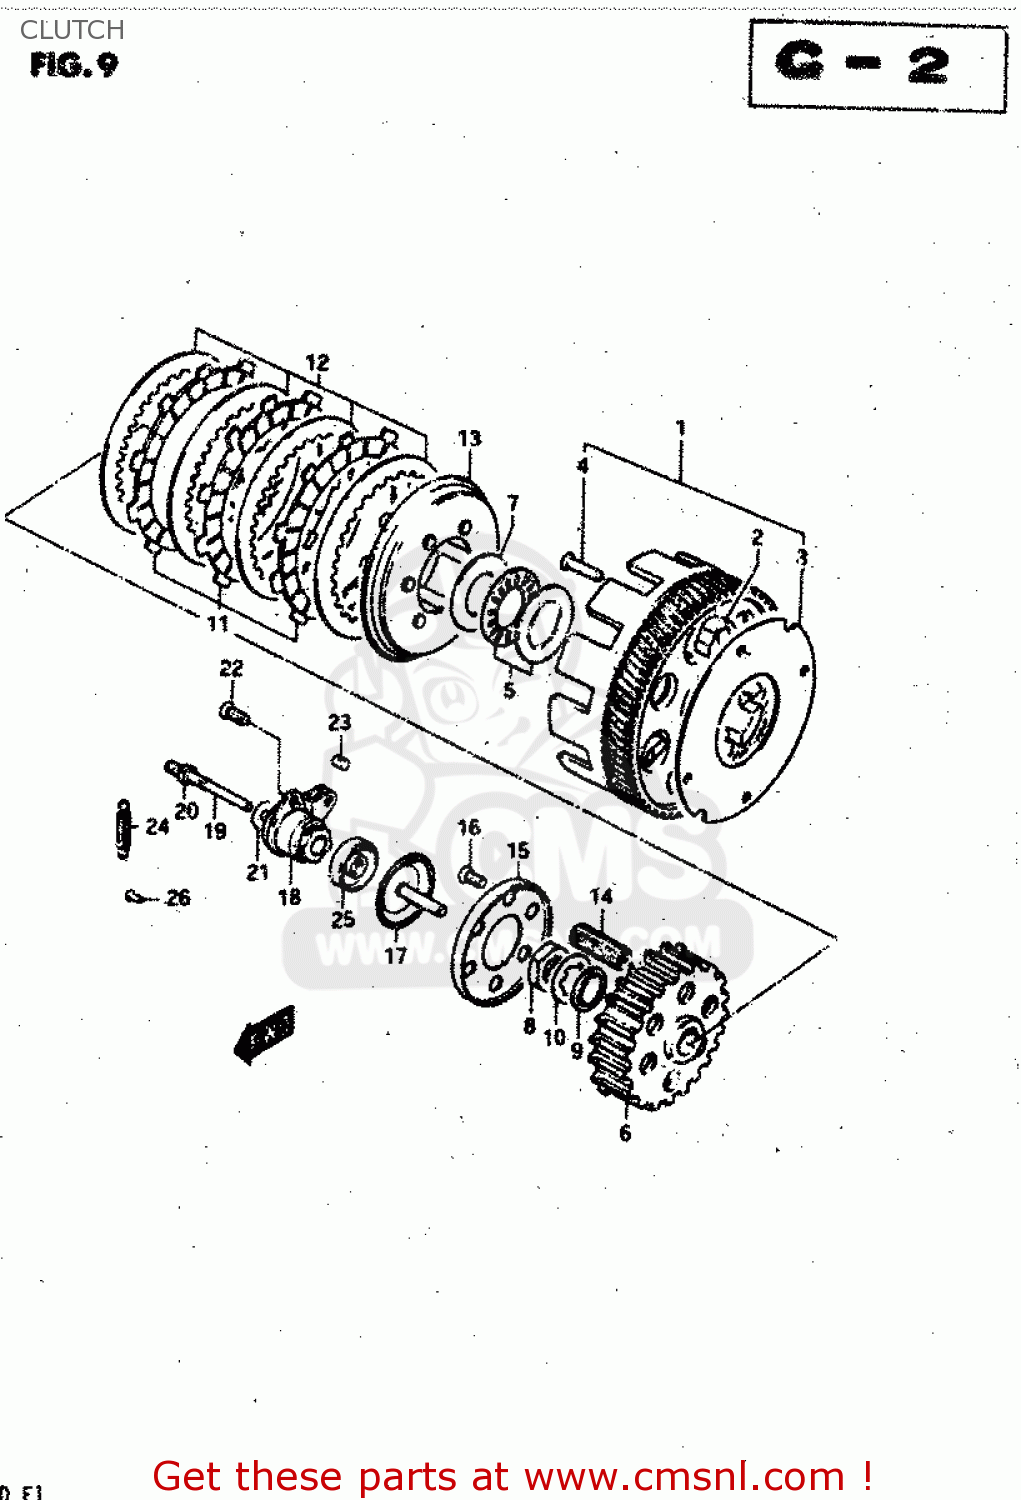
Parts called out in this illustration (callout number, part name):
1	GEAR,PRIMARY DRIVEN(NT:73)
2	DUMPER
3	PLATE
4	RIVET
5	BEARING(21X32X2.85)
6	HUB,CLUTCH SLEEVE
7	WASHER
8	NUT
9	WASHER,LOCK
10	WASHER,LOCK
11	PLATE,CLUTCH DRIVE (MCA)
12	PLATE,CLUTCH DRIVEN (NAS)
13	DISC,CLUTCH PRESSURE
14	SPRING
15	PLATE,CLUTCH OUTER
16	SCREW
17	PIECE,CLUTCH PUSH
18	SCREW ASSY,CLUTCH RELEASE
19	SCREW(6X45)
20	NUT 6MM
21	WASHER(6.5X16X1.2)
22	SCREW
23	PIECE,RELEASE ARM END
24	SPRING
25	SEAL,OIL(4.5X26X6)
26	RIVET
